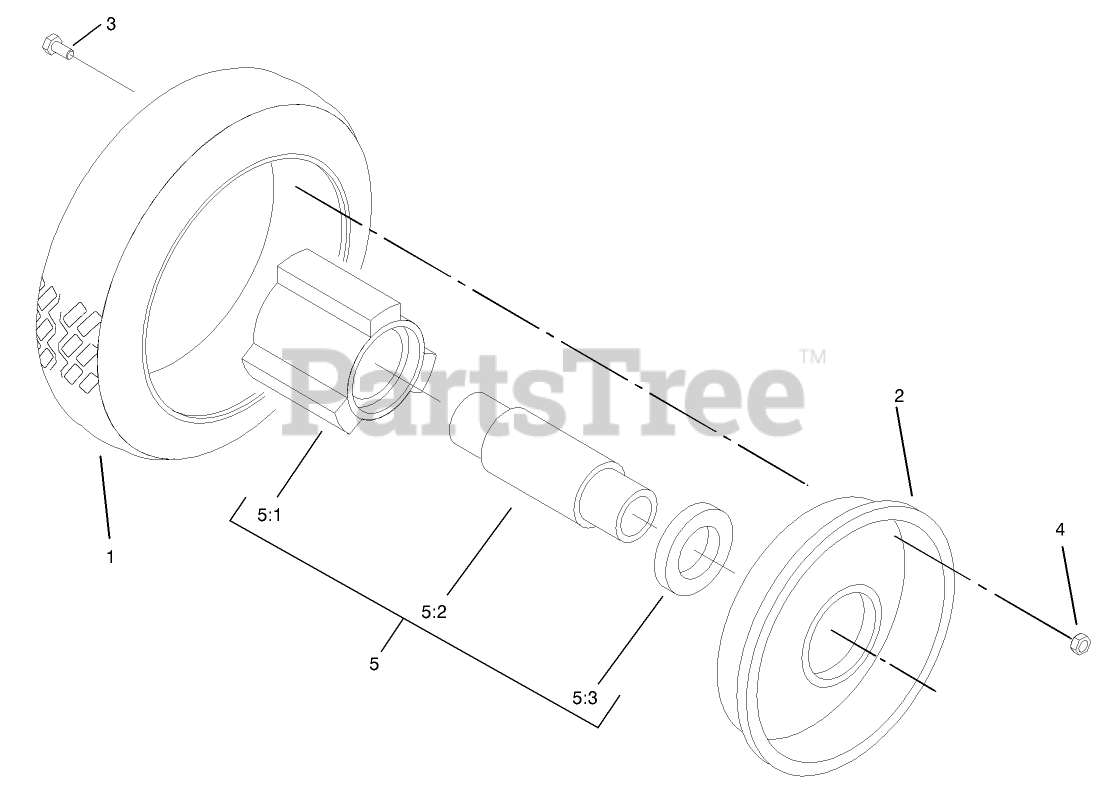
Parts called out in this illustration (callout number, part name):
3	SCREW-HH
4	NUT-LOCK, NI
5	Loose Parts Package
5:1	HUB-BEARING
5:2	SPACER-BEARING
5:3	BEARING-WHEEL
